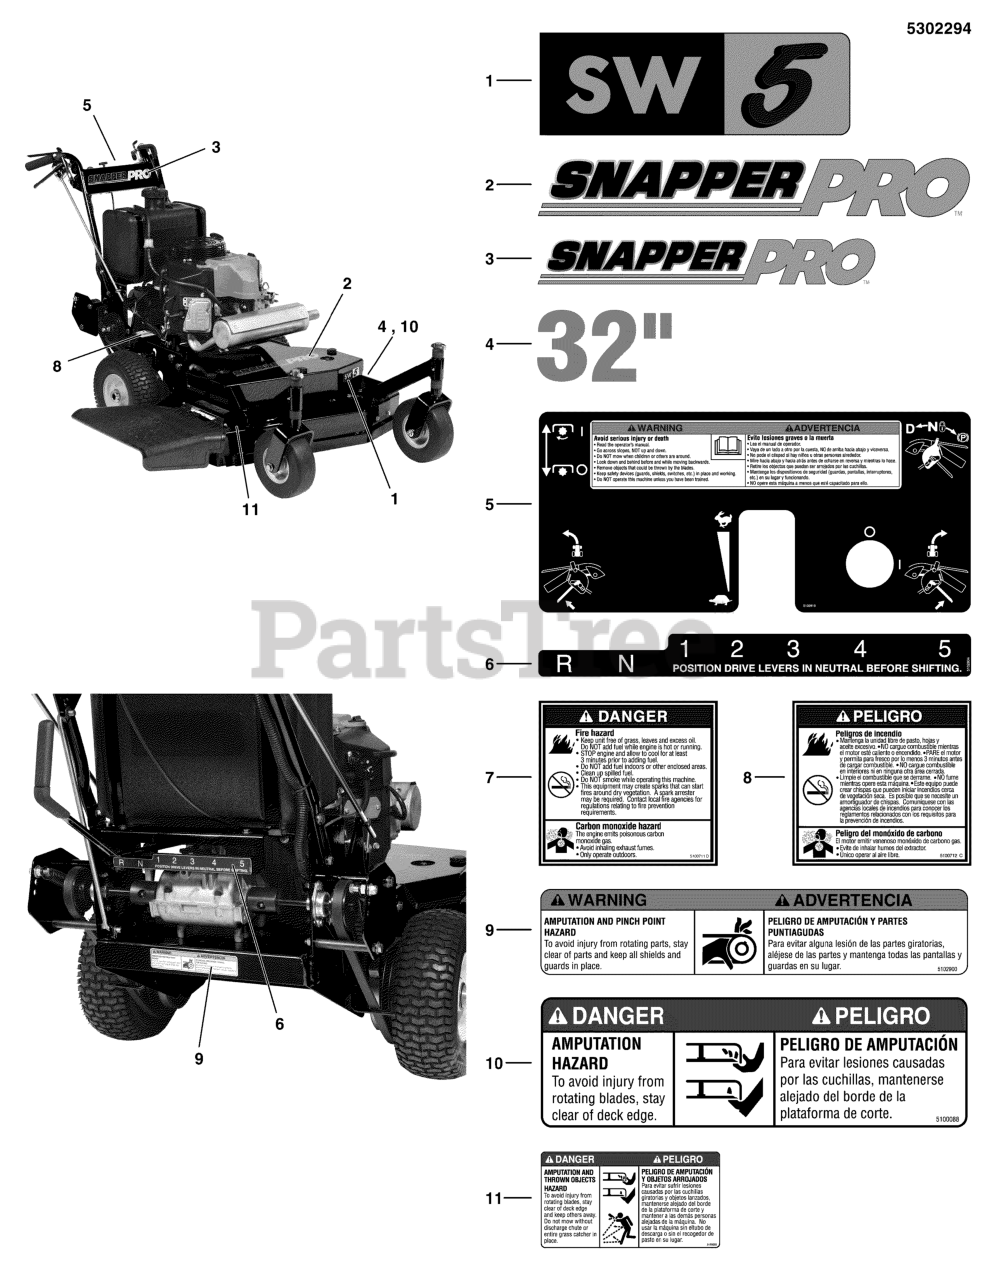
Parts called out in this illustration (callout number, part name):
1	DECAL, SW5
2	DECAL, SNAPPER PRO, FRONT
3	DECAL, SNAPPER PRO, 12.87 X 1.83
4	DECAL, 32
5	DECAL, CONTROL PANEL, BELT DRIVE
6	DECAL, GEAR SELECTOR, BELT DRIVE
7	DECAL, DANGER
8	DECAL, DANGER, FIRE (SP)
9	DECAL, PINCH POINT
10	DECAL, DANGER, MOWER
11	DECAL, DANGER,MOWER DISCHARGE, 5.5 X 3.0
